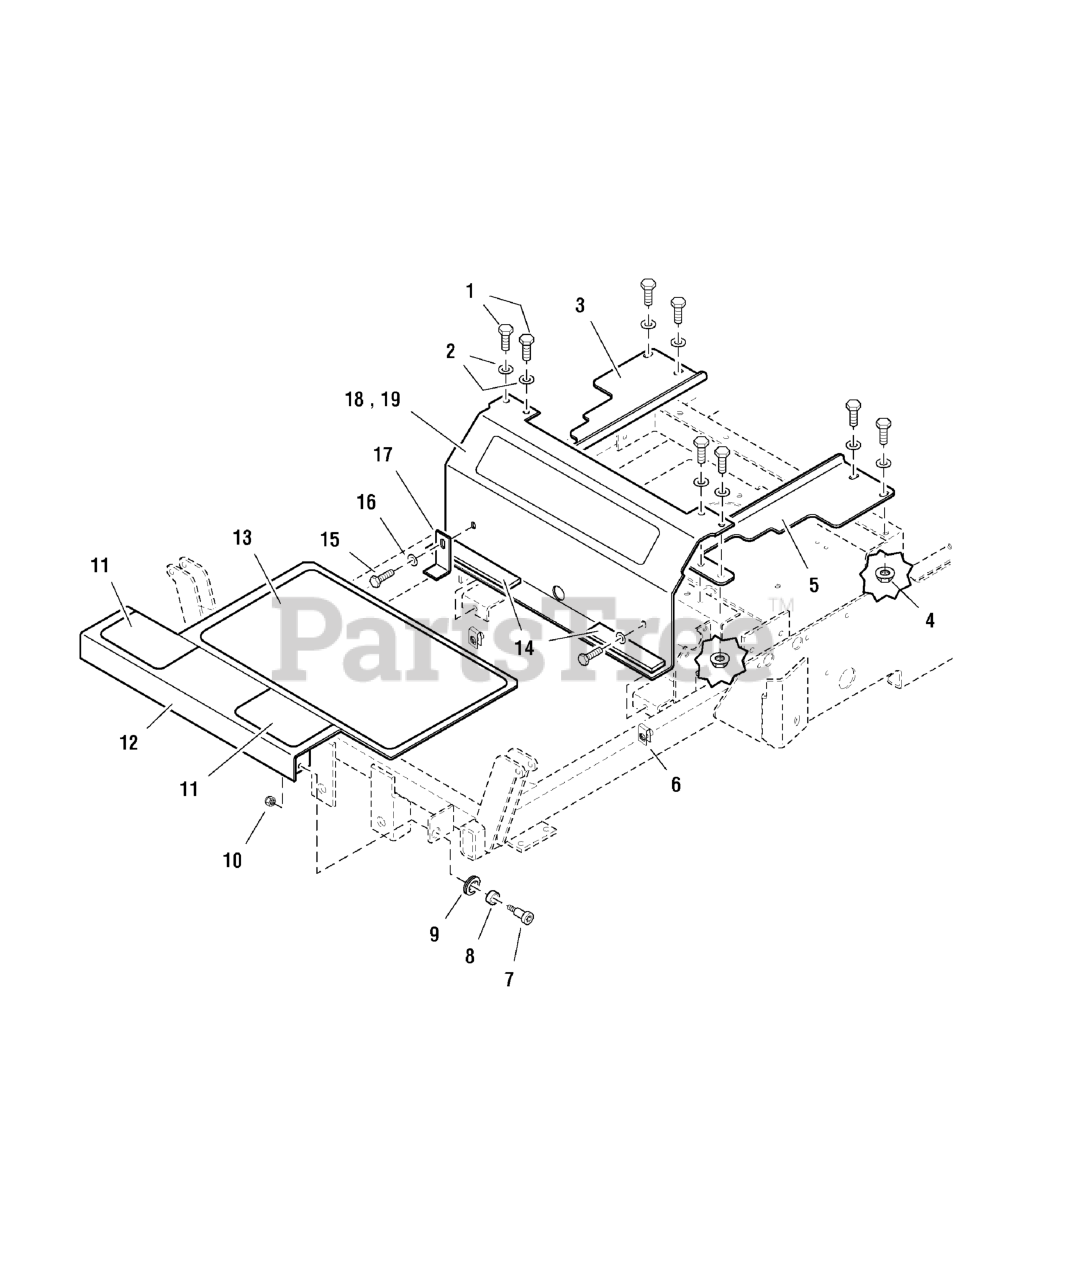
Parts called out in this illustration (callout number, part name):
1	BOLT, 3/8-16 X 1" GD5 CZ
2	WASHER, 3/8 SAE
3	SHIELD - RH
4	NUT, 3/8-16 Hex Serrated Flange
5	SHIELD - LH
6	BODY CLIP, 5/16-18-7GA MATERIAL
7	SHOULDER BOLT, 3/8 x 5/8
8	SLEEVE
9	GROMMET
10	NUT, 5/16-18 Hex Nylon Lock
11	SAFETY WALK
12	FLOOR PAN
13	SAFETY WALK, 11.50 X 19.00
14	RUBBER PAD
15	BOLT, 5/16-18 X 3/4 GD5
16	WASHER, 5/16" SAE
17	HOLD DOWN
18	BRAKE COVER PANEL ASSEMBLY
19	BRAKE COVER PANEL ASSEMBLY, Export Model
